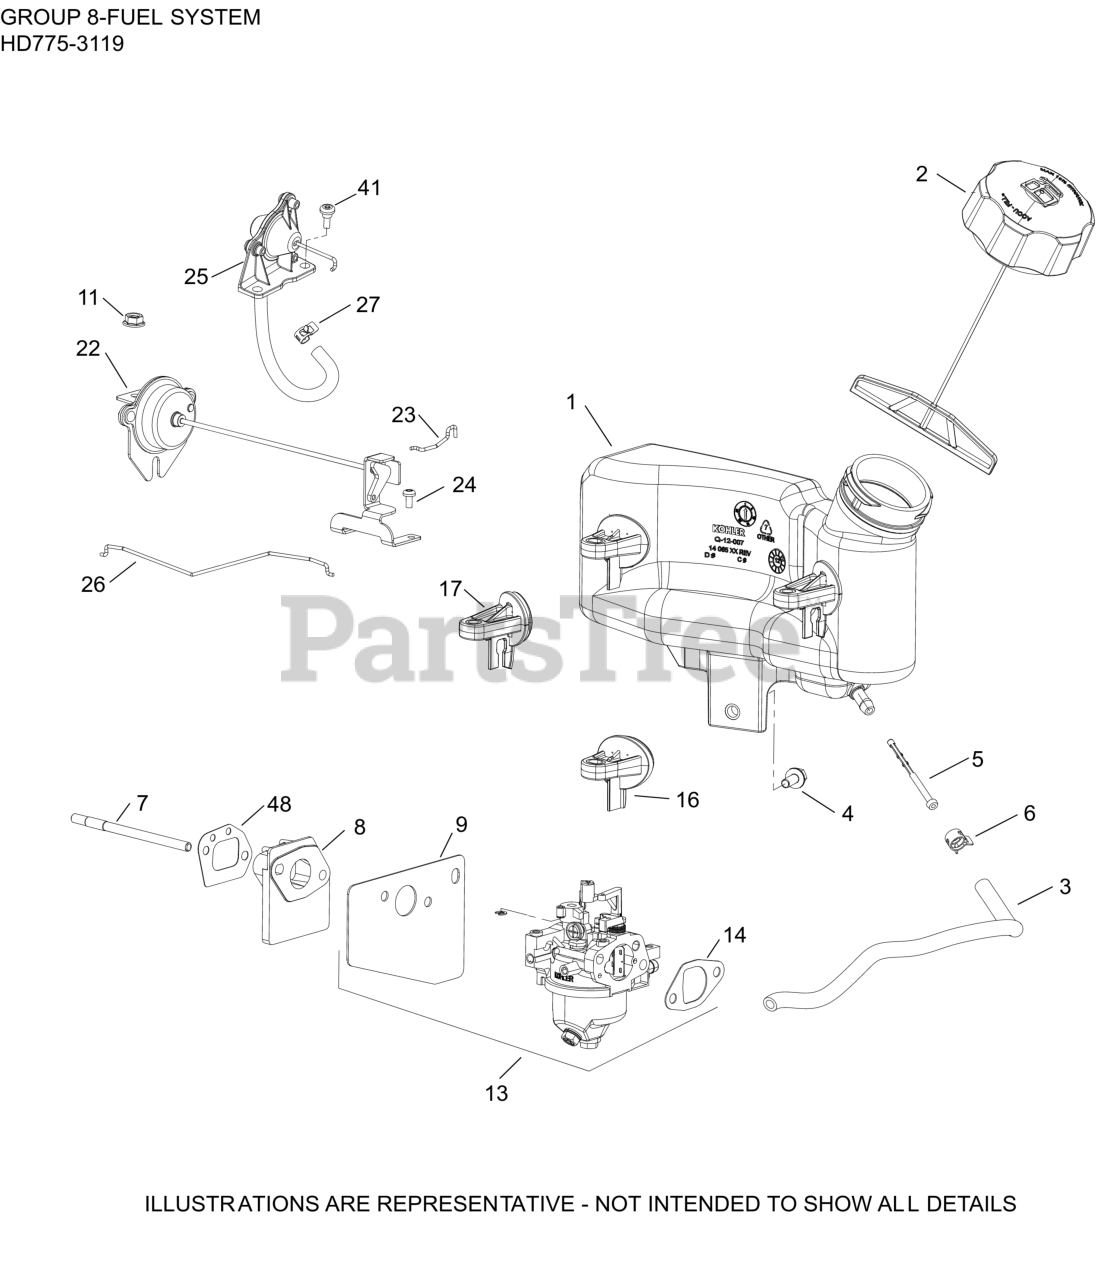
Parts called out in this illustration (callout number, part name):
1	TANK, FUEL
2	FUEL CAP ASSEMBLY
3	HOSE, FUEL LOW-PERMEATION
4	SCREW, HEX FLANGE (M6)
5	FILTER, FUEL IN-NIPPLE
6	CLAMP, HOSE
7	STUD,M6X1.0X100.2MM
8	KIT, SPACER
9	KIT, CARBURETOR HEAT SHIELD GASKET
11	NUT, HEX FLANGE (M6) - USE 14 100 16-S
13	KIT, CARBURETOR 13 MM AUTO CHOKE
14	KIT, INTAKE GASKET
16	BRACKET, FUEL TANK-DISCONTINUED
17	BRACKET, FUEL TANK-DISCONTINUED
22	ARM ASSEMBLY, AUTO CHOKE
23	LINKAGE AUTO CHOKE
24	SCREW, M4 THREAD FORMING
25	DIAPHRAGM, ASSEMBLY
26	LINKAGE, CHOKE
27	CLAMP, HOSE
41	SCREW, SHOULDER
48	GASKET SPACER
NI	KIT,HIGH AL(4000-8000 FT)USE 14 755 04-S
NI	KIT, HIGH ALTITUDE (ABOVE 8,000 FT.)
NI	KIT, CARBURETOR REPAIR (RUIXING)
